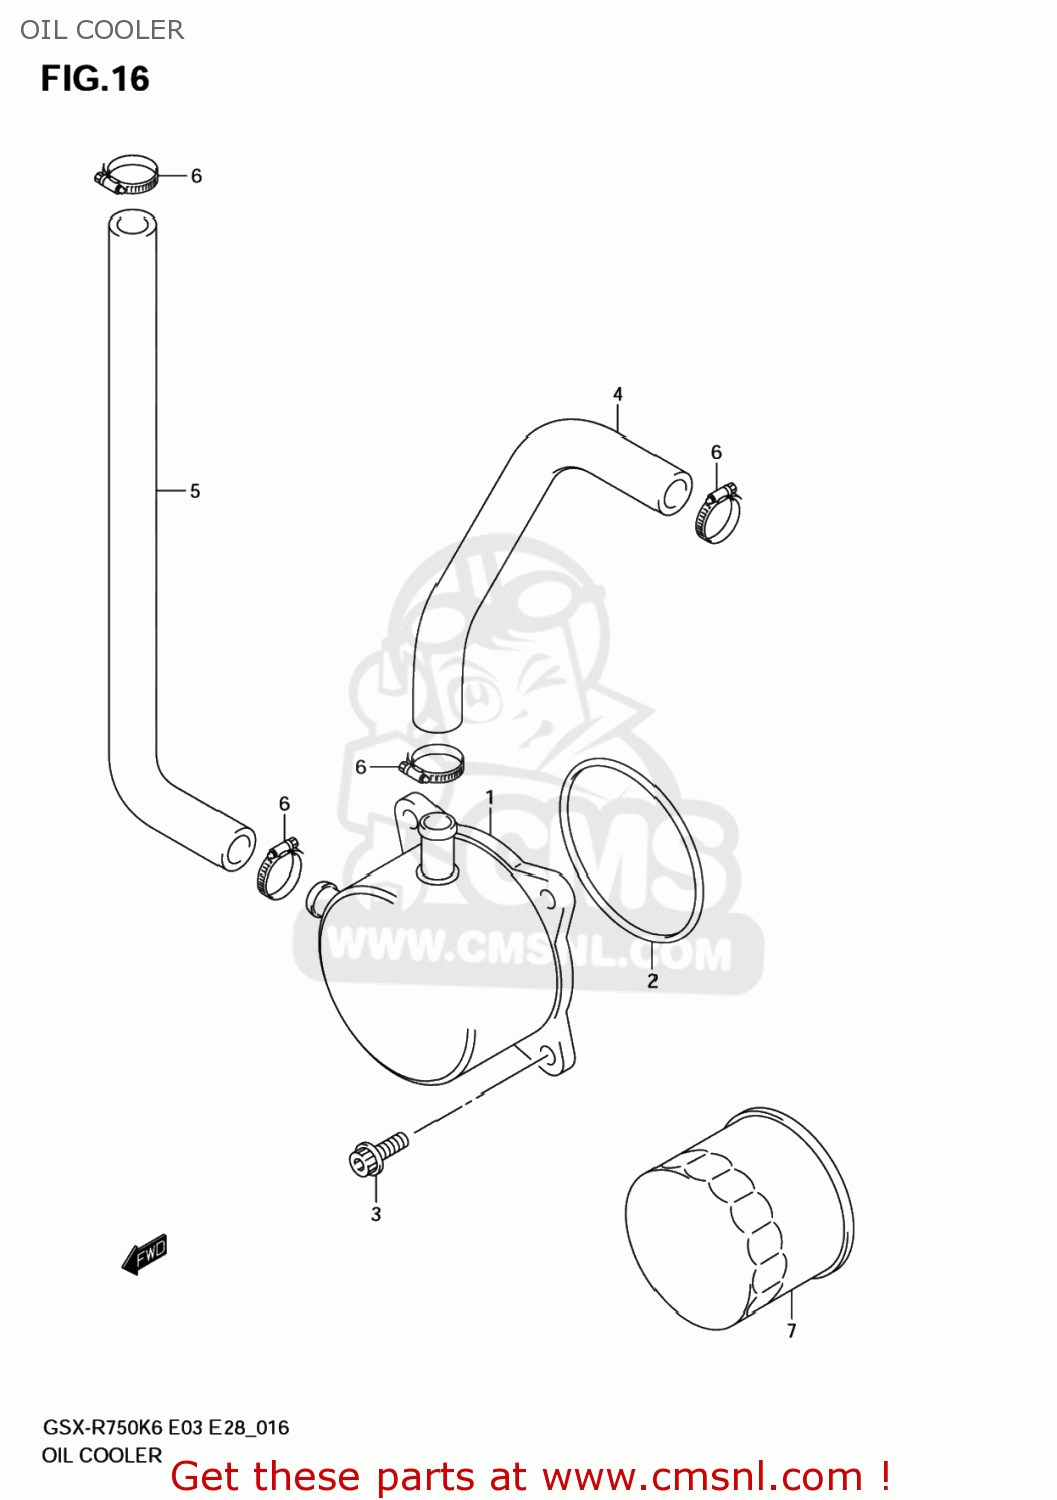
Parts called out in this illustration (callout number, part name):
1	COOLER ASSY,OIL
2	O RING(D:3.1,ID:63.9)
3	BOLT (6X16)
4	HOSE,OIL COOLER WATER INLET
5	HOSE,OIL COOLER WATER OUTLET
6	CLAMP
7	FILTER ASSY,EN
